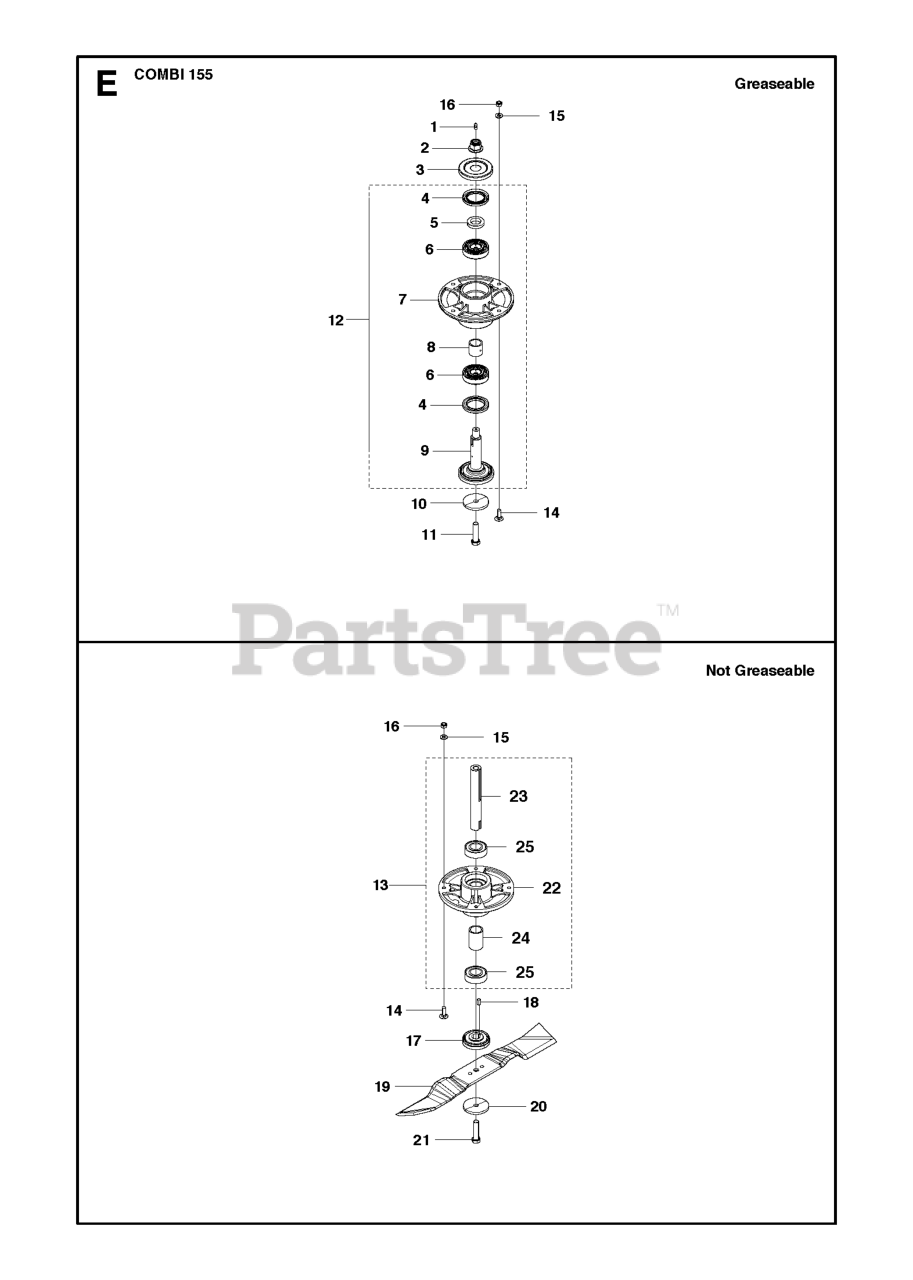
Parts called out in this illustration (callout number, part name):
1	GREASE NIPPLE
6	BALL BEARING 6305 C3
15	LOCKNUT M8
16	WASHER BRB 8.4X17
22	BEARING HOUSING
25	BALL BEARING
